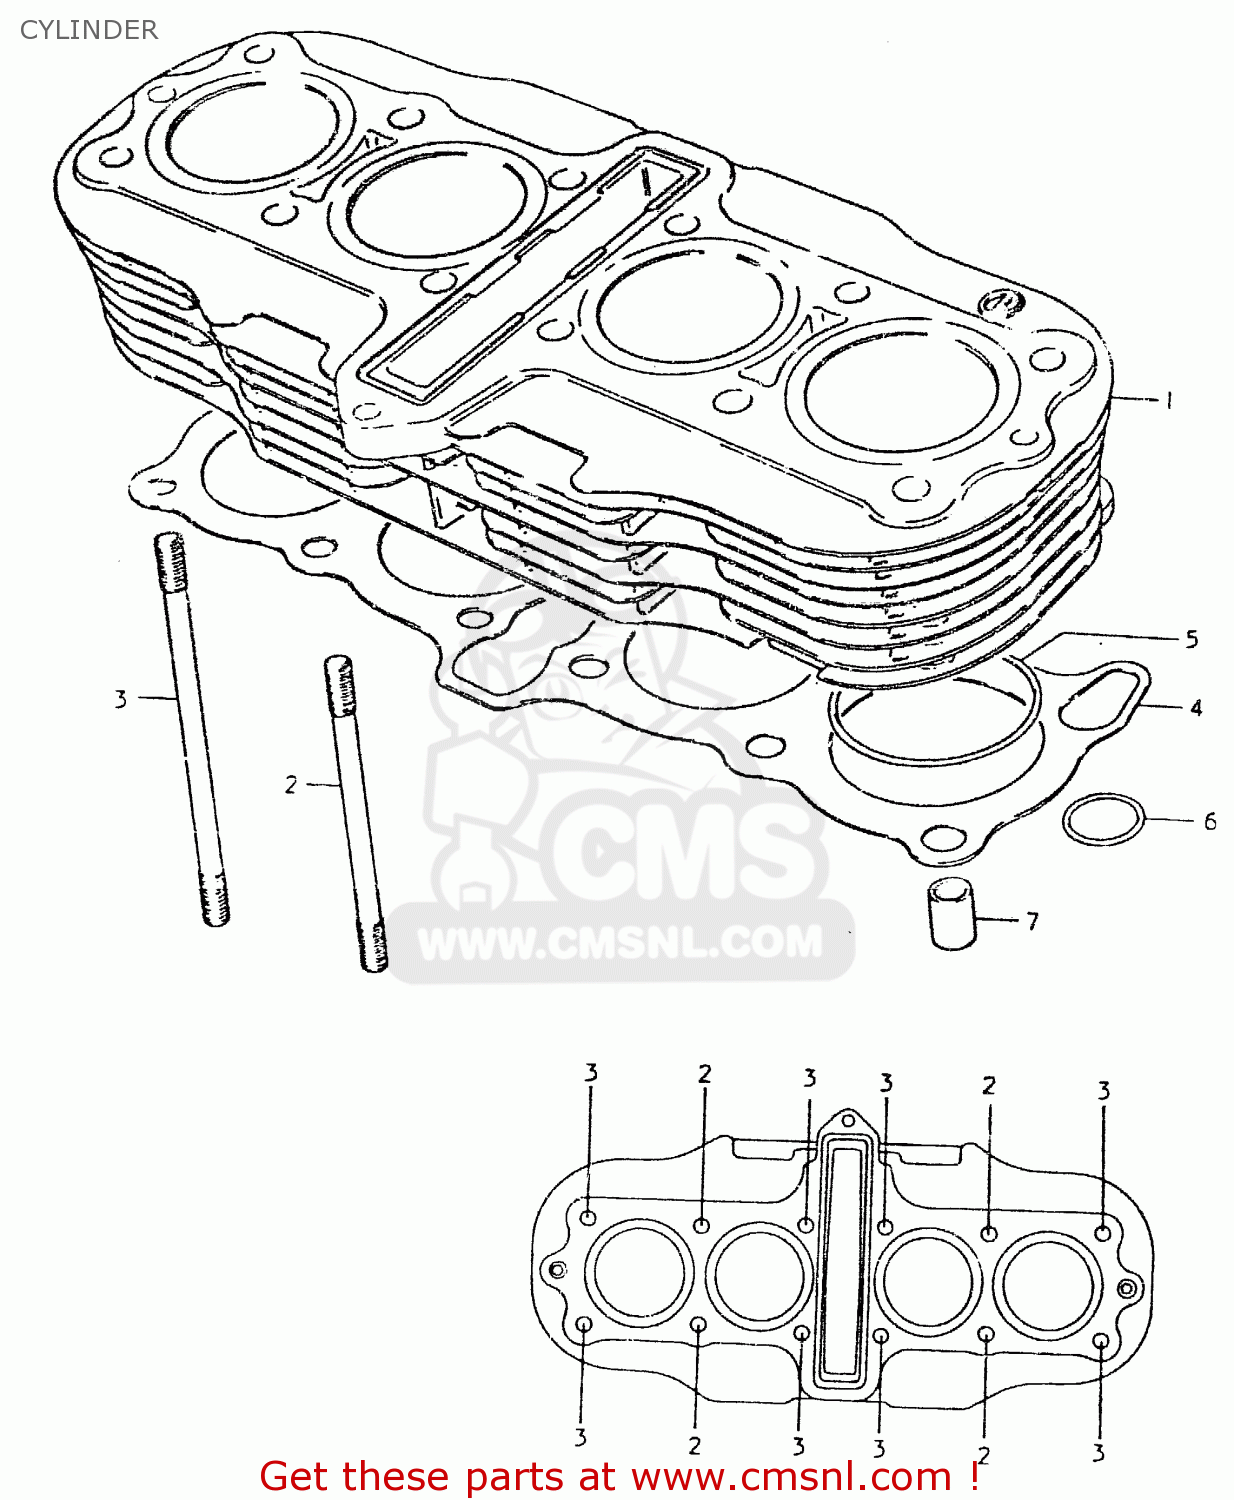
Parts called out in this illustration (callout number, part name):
1	CYLINDER
2	BOLT,STUD
3	BOLT,STUD
4	GASKET,CYLINDER (MCA)
5	O RING(D:2,ID:61)
6	INVALID PARTNUMBER
7	PIN
